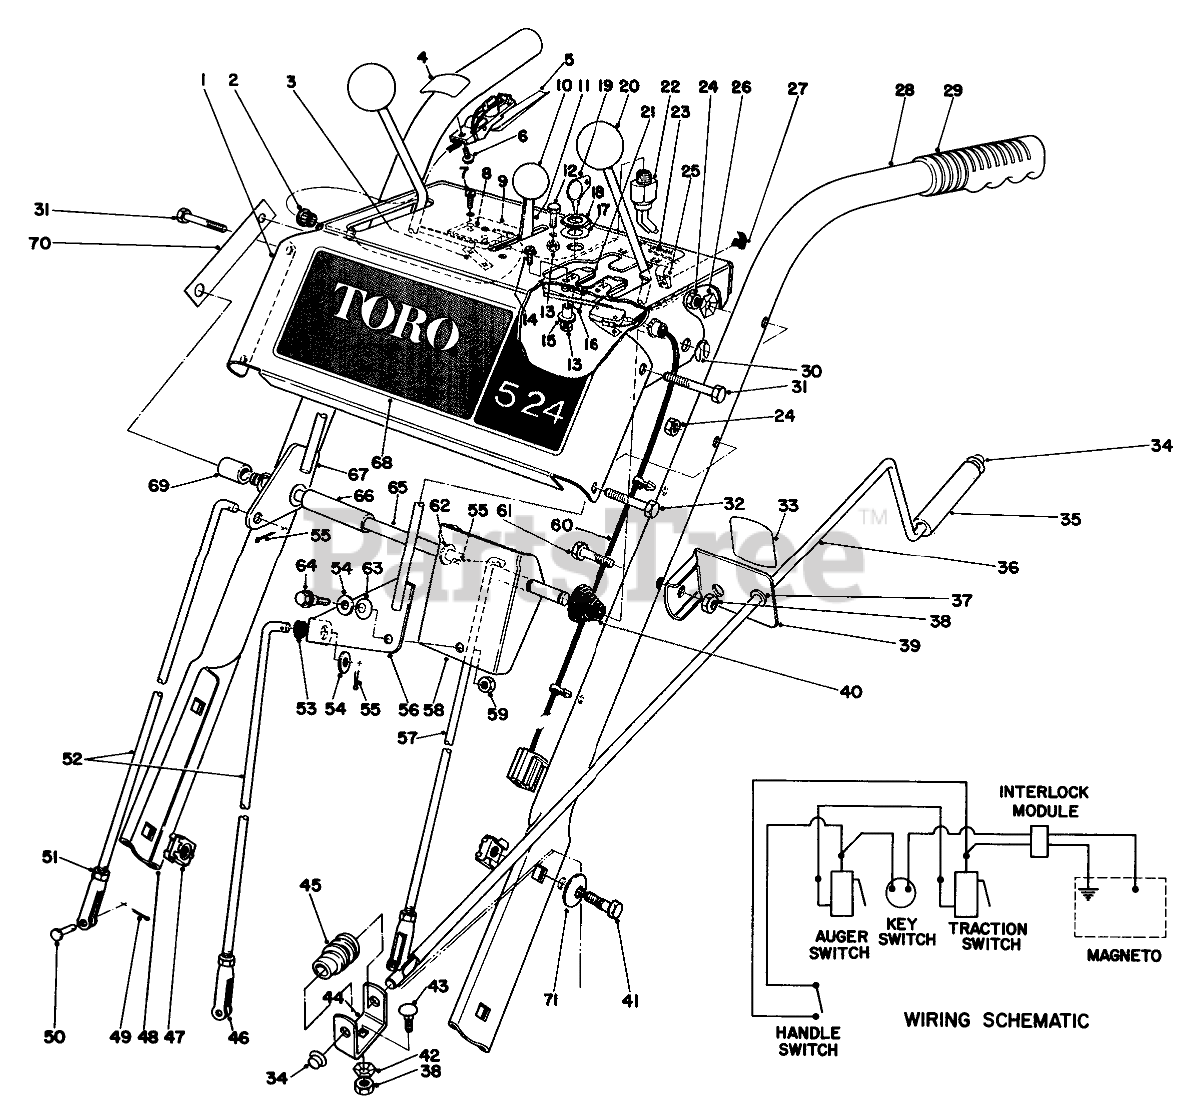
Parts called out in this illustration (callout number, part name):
1	ESCUTCHEON PLT B
2	BUSHING NYLON
3	NUT-SPEED
4	INTERLOCK DECAL
5	INTERLOCK HDLE SWITCH
6	SCREW
7	Pan Head Machine Screw
8	SWITCH-MICRO
9	SWITCH MTG PAD
10	CONTROL KNOB
11	THROTTLE CONTROL
12	HEX HEAD SEMS 10-24X1/2
13	NUT-LOCK, NI
14	10-24 X 7/8 RND HD MS
15	INTERLOCK SPACER
16	INTERLOCK SPRING
17	WASHER-TOOTH, INTERNAL
18	NUT-HH
19	Key
21	Slide Interlock
22	On-Off Switch (Incl. Ref. #17 & 18)
23	INSTR DECAL
24	NUT-LOCK, CONE
25	WIRE CLAMP
26	Washer
27	Mounting Stud
28	LEFT HANDLE
29	Grip Handle
30	RING-CLIP
31	SCREW-HH
32	SCREW-HH
33	CHUTE DECAL
34	RETAINER-PUSH ON
35	GRIP-CONTROL, CHUTE
36	CHUTE CONTROL ROD
37	Bushing
38	NUT-LOCK, NI
39	Chute Control Rod Mounting (Incl. Ref. #33 & 37)
40	CONICAL SPRING
41	SCREW-HH
42	WASHER-LOCK
43	BOLT-CARR
44	BRACKET-WORM
45	GEAR-WORM, CHUTE
46	CLEVIS
47	Retained Nut
48	HANDLE RIGHT
49	PIN-COTTER
50	PIN-CLEVIS
51	NUT-HJ
52	SPEED SELECTOR ROD
53	GROMMET-RUBBER
54	WASHER-FLAT
55	PIN-COTTER
56	SHIFT LEVER WA
57	TRACTION CONTROL ROD
58	SHIFT BRACKET
59	NUT-LOCK, CONE
60	WIRE HARNESS INTERLOC
61	SCREW-HH
62	WASHER-FLAT
63	7/16 SPRING WASHER
64	SHOULDER SCREW
65	PIVOT ROD
66	SHIFT LEVER SPACER
67	LEVER WA
68	ESCUTCHEON DECAL
69	AUGER LEVER SPACER
70	ESCUTCHEON SUPT STRAP
71	WASHER-SPRING
